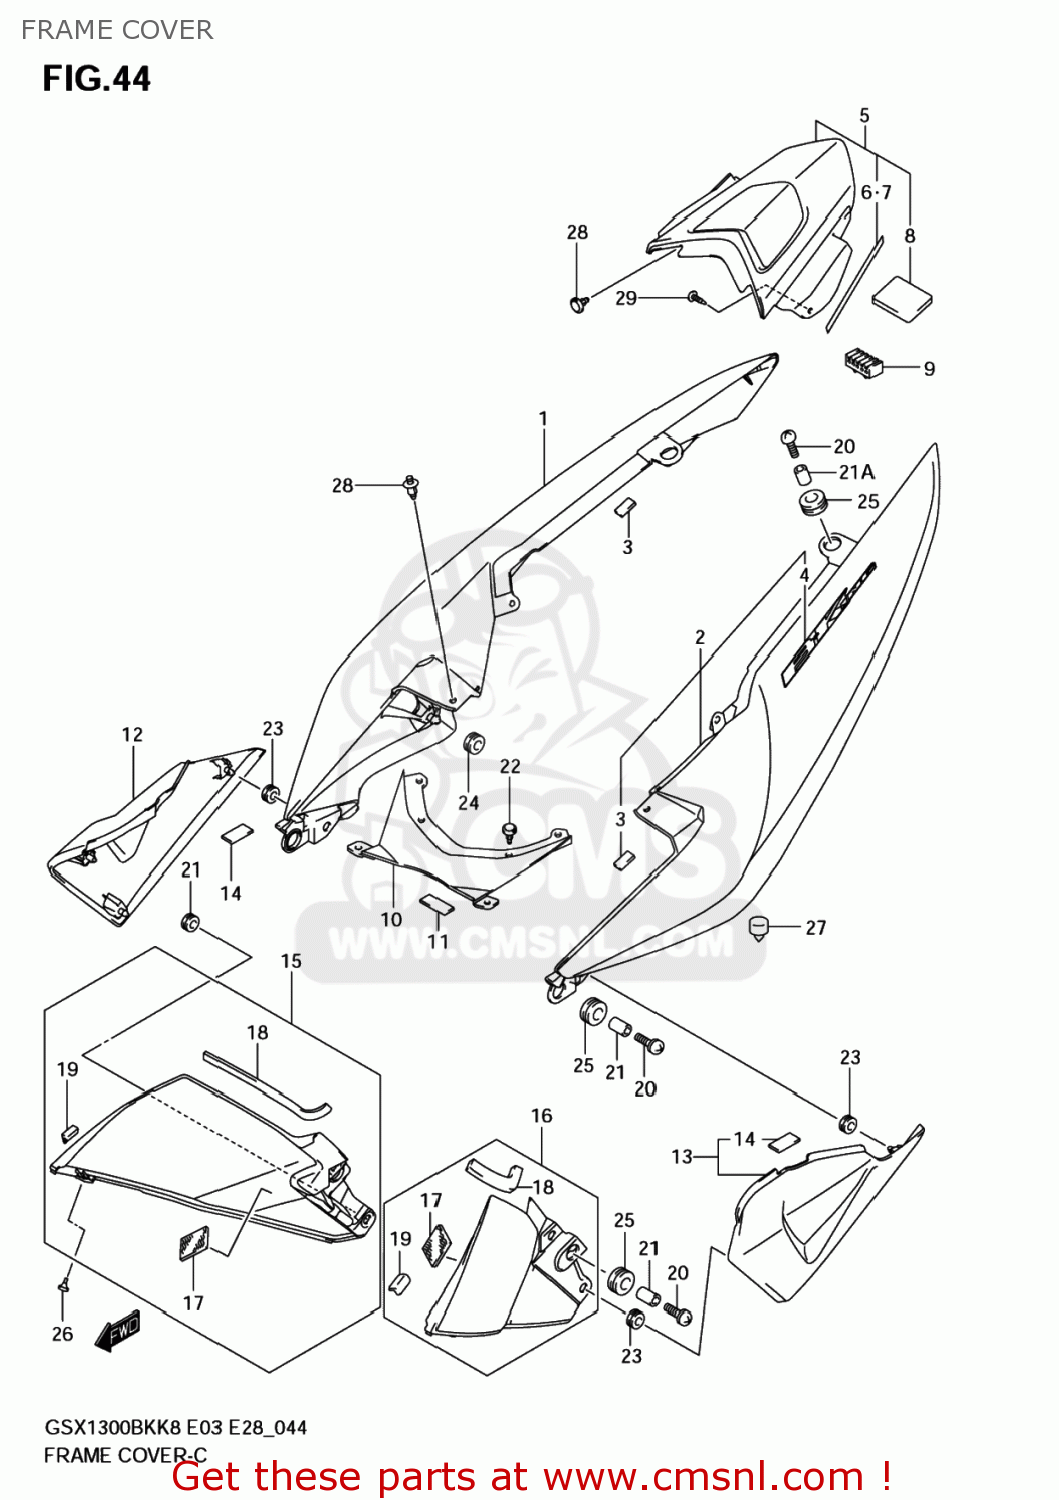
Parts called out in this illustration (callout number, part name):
1	COVER,FRAME,R(GRAY)
2	COVER,FRAME,L(GRAY)
3	CUSHION,SEAT TAIL COVER LWR RR
4	EMBLEM,FRAME COVER
5	COVER,FRAME CTR
6	TAPE,FRAME COVER CTR,R
7	TAPE,CTR COVER,L
8	CUSHION,CTR COVER
9	CUSHION,SEAT(40X20X15)
10	LID,FRAME COVER CTR
11	CUSHION,SEAT TAIL COVER LWR RR
12	COVER,FRAME SIDE,R(BLACK)
13	COVER,FRAME SIDE,L(BLACK)
14	CUSHION,SEAT TAIL COVER LWR RR
15	COVER,FRAME SIDE FR,R(BLACK)
16	COVER,FRAME SIDE FR,L(BLACK)
17	FASTENER
18	CUSHION,FR SIDE COVER
19	MOLDING,FRAME COVER
20	SCREW(6X20)
21	SPACER(6.5X12X9)
21A	SCREW
22	PLUG(OD:10)
23	CUSHION
24	CUSHION
25	CUSHION
26	CUSHION
27	CUSHION
28	CLIP
29	SCREW
